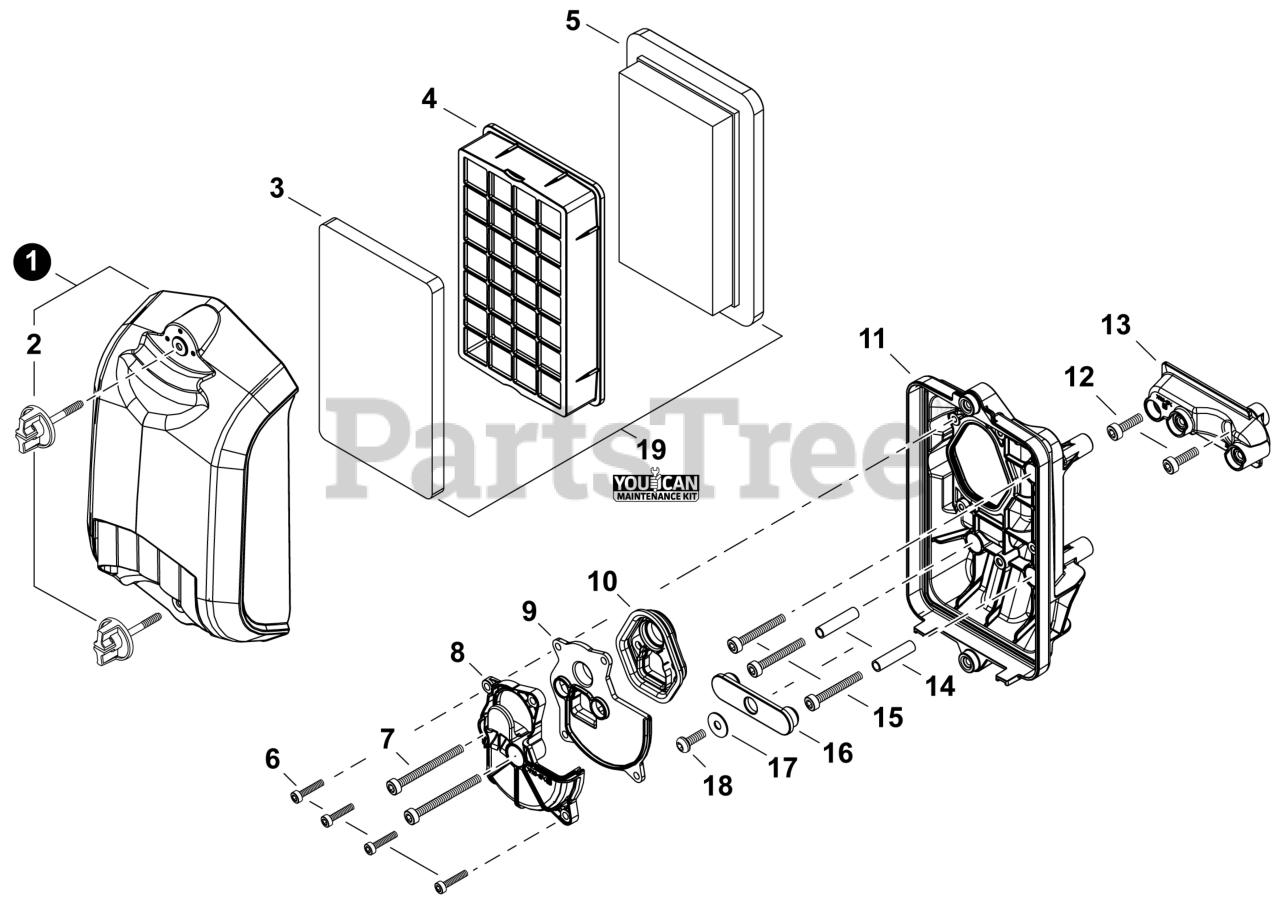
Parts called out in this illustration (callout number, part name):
1	COVER ASSY, AIR FILTER
2	THUMBSCREW
3	PRE-FILTER, FOAM
4	RETAINER, PRE-FILTER
5	FILTER, AIR
6	BOLT, TORX 4x20
7	BOLT, TORX 5x55
8	PLATE, PREVENT
9	PLATE, SEAL
10	SEAL, AIR FILTER CASE
11	CASE, AIR FILTER
12	BOLT, TORX 5x20
13	BRACKET, AIR FILTER
15	BOLT, TORX 5x40
16	GROMMET, PLUG
17	WASHER 5.5x16x0.8
18	BOLT, TORX 5x16
19	TUNE-UP KIT - YOUCANT
